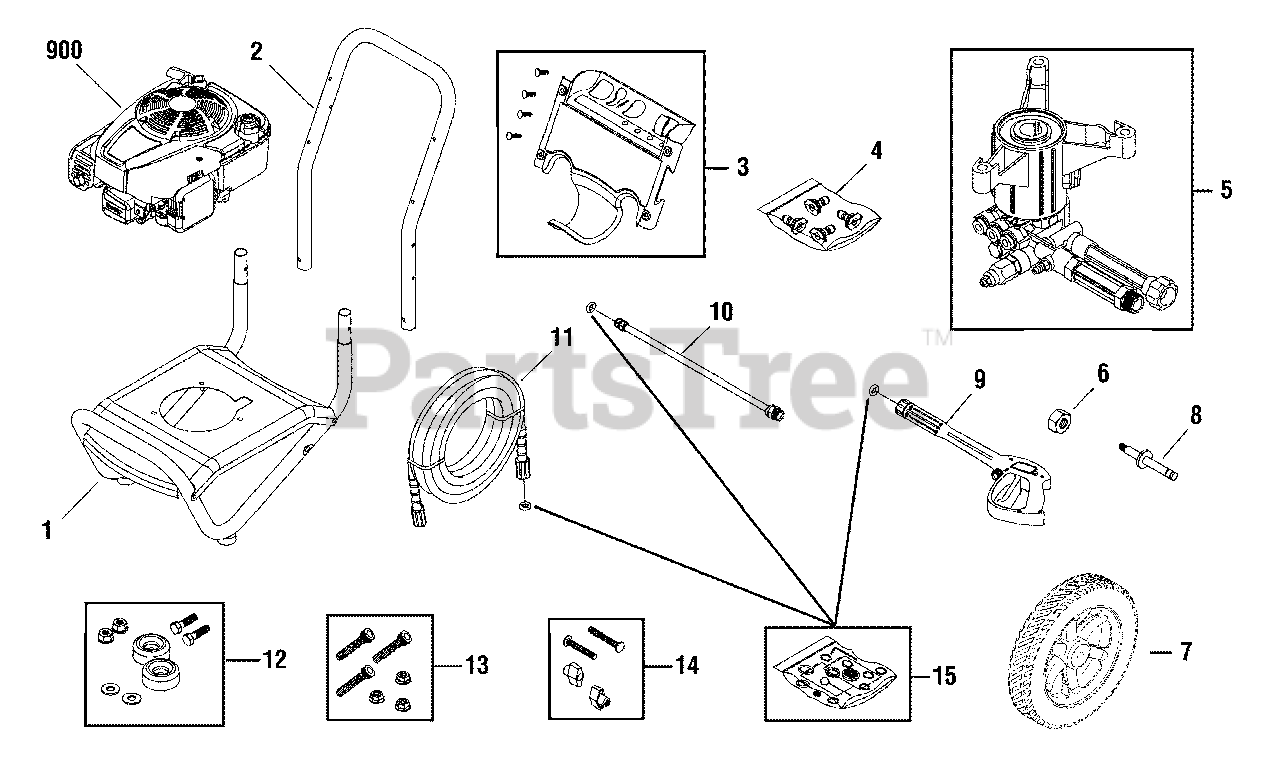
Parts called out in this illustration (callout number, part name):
6	NUT
9	GUN
10	EXTENSION, QC
11	HOSE
12	MOUNT, Vibration
13	KIT, Hardware Pump Mounting
15	KIT, O-Ring
900	ENGINE
